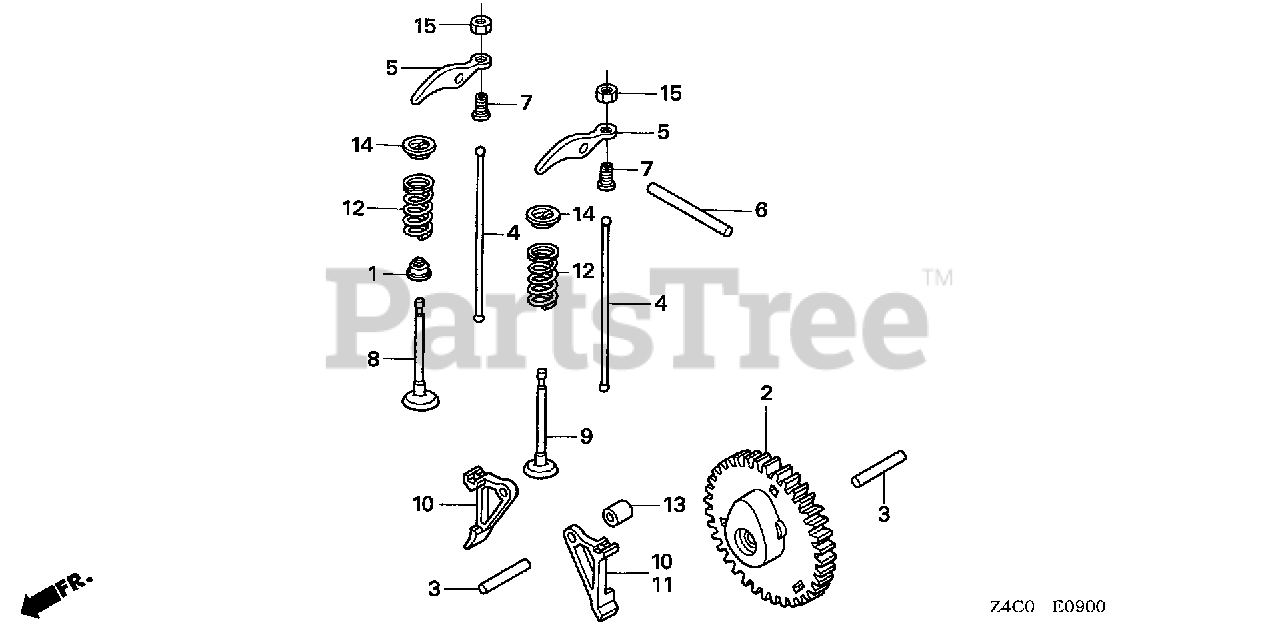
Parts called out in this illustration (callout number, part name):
1	SEAL, VALVE STEM
2	CAMSHAFT ASSY.
3	ROLLER (5X29.8)
5	ARM, VALVE ROCKER
6	ROLLER (4X37.8)
7	PIVOT, ROCKER ARM
8	VALVE, IN.
9	VALVE, EX.
10	LIFTER, VALVE
11	LIFTER, EX. VALVE
12	SPRING, VALVE
13	COLLAR, LIFTER
14	RETAINER, VALVE SPRING
15	NUT, TAPPET ADJUSTING
